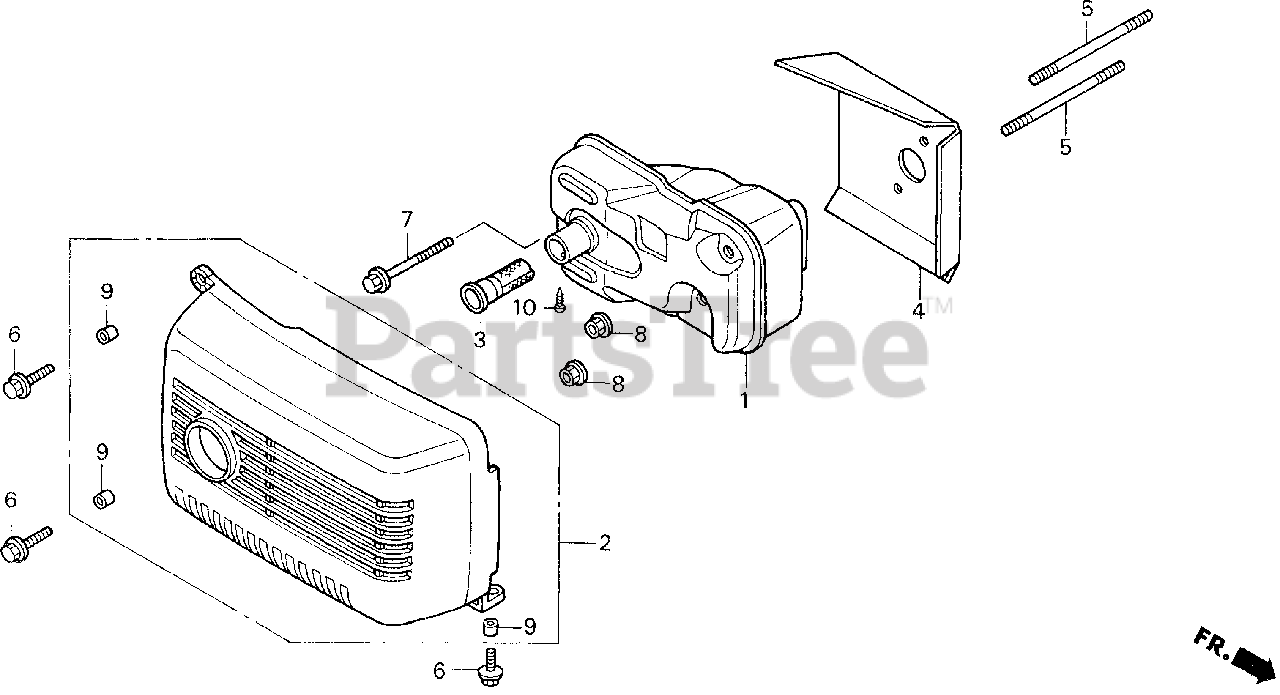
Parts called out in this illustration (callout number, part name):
1	MUFFLER
2	PROTECTOR, MUFFLER
3	ARRESTER, SPARK
4	GUIDE, AIR
5	BOLT 2, STUD (5X55)
6	BOLT, FLANGE (5X16)
7	BOLT, FLANGE (5X35)
8	NUT, SELF-LOCK (5MM)
9	COLLAR, TOP COVER
10	SCREW, TAPPING (4X8)
